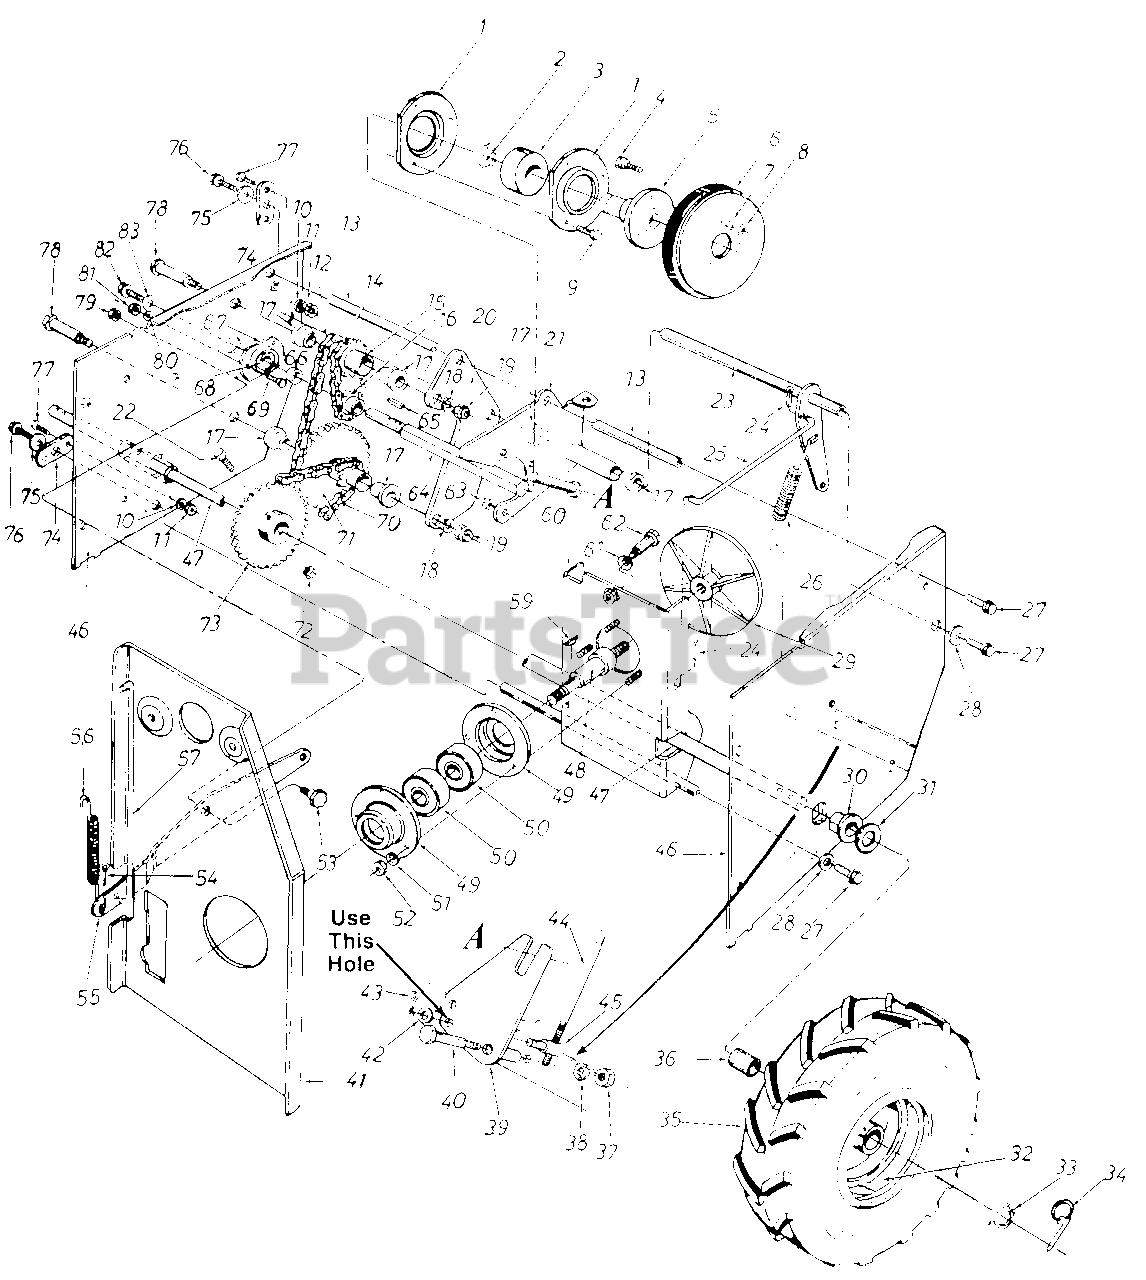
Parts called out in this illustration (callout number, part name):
1	Bearing Houslng
2	Snap Ring-1.0" Dia.
3	Ball Brg. .25MM x 52MM x 15MM Thk.
4	Hex Sems Bolt 5/16-18 x .75" Lg.
5	Friction Wheel Adapter
6	Friction Wheel Ass'y.
7	L-Wash. 5/16" I.D.
8	Hex Nut 5/16-18 Thd.
9	Hex Bolt 1/4-28 x .62" Lg.
10	L-Wash. 1/4" I.D.*
11	Hex Nut 1/4-20 Thd.
12	#41 Chain-1./2" Pitch x 43 Links
13	Sliding Support Axle
14	#41 Chain-1/2" Pitch x 19 Links
15	9 and 14 Teeth Sprocket Hub Ass'y.
16	8 Teeth Sprocket
17	Flange Bearing .63" I.D.
18	L-Wash. 3/8" I.D.-Heavy Duty
19	Hex L-Jam Nut 3/8-24 Thd.
22	Hex Bolt 5/16-24 x 1.75" Lg.
23	Drive Clutch Brkt. Ass'y.
24	Inter. Cot. Pin 5/16" Dia.
25	Drive Clutch Rod .31" Dia. x 7.38" Lg.
26	Extension Spring .73" O.D. x 4.31" Lg.
27	Hex L-Bolt 5/16-18 x .62" Lg.
28	Fl-Wash. .345" I.D. x .75" O.D.
29	Aluminum Drive Plate
30	Flange Brg. w/Flats 1" I.D.
31	Fl-Wash. .62" I.D. x 1.25" O.D.
32	Tubeless Air Valve
33	Snap Ring 1" Shaft
34	Klick Pin Ass'y.
35	Wheel Ass'y. Comp. 16 x 4.5-L. H.
36	Bearing 1.0" I.D. x 1.12 O.D. x 1.0" Lg.
37	Hex Jam Nut 3/8-16 Thd.
38	L-Wash. 3/8" I.D.
41	Engine Brkt. Ass'y.
42	Fl-Wash. .344" I.D. x .62" O.D.
43	Cotter Pin 3/32" Dia. x .75" Lg.
44	Shifting Rod
45	Adjustment Ferrule
46	Frame Ass'y.
47	Free Wheeling Axle
48	Drive Plate Spindle
49	Bearing Housing
50	Ball Brg. .787" I.D. x 1.85" O.D.
51	L-Wash. 5/16" I.D.
52	Hex Nut 5/16-18 Thd.
53	Shld. Bolt .625" Dia. x .170" Lg.
54	Inter Cotter Pin 5/16" Dia.
55	Auger Clutch Brkt.
56	Extension Spring .38" O.D. x 3.18" Lg.
57	Auger Clutch Rod .31" Dia. x 10.62" Lg.
59	#61 Hi-Pro Key 3/16" x 518" Dia.
62	Shld. Bolt
63	Hex Ins. Jam Nut 1/4-28 Thd.
64	Hex Shaft
65	#9 Hi-Pro Key 3/32" x 5/8" Dia.
66	Spacer .51" I.D. x .69" O.D.
67	Bearing Housing
68	Ball Bearing
69	Hex Bolt 1/4-20 x .62" Lg.
70	#420 Chain .50" Pitch x 37 Links
71	9 and 32 Teeth Sprocket Hub Ass'y.
72	Hex L-Nut 5/16-24 Thd.
73	28 Teeth Sprocket Hub Ass'y.
74	Pivot Axle Brkt.
75	Fl-Wash. .345" I.D. x .75" O.D.
76	Hex L-Bolt 5/16-18 x .62" Lg.
77	Hex Bolt 1/4-20 x .62" Lg.
78	Sprocket Hub Tubing 1.880" Lg.
79	Hex Cent. L-Nut 3/8-16 Thd.
80	L-Wash. 1/4" I.D.
81	Hex Nut 1/4-20 Thd.
82	Hex L-Bolt 5/16-18 x .62" Lg.
83	Fl-Wash. .345" I.D. x .75" O.D.
